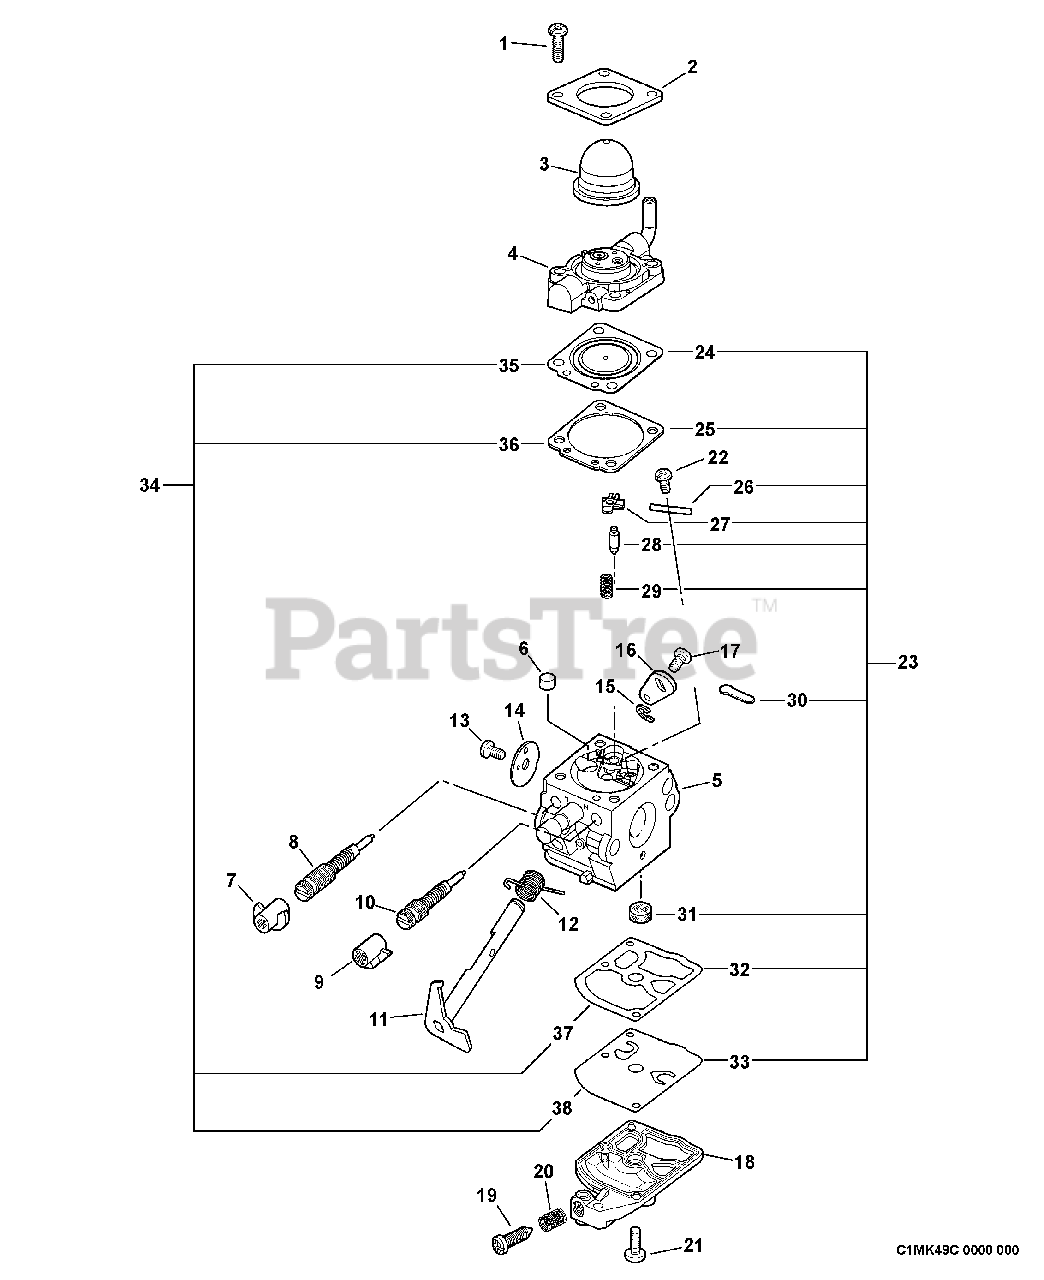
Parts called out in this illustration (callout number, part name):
2	RETAINER, PURGE BULB
3	BULB, PURGE
4	BODY ASSY, PURGE
5	BODY, CARBURETOR
6	NOZZLE, CHECK VALVE
7	CAP, LIMITER - WHITE
8	NEEDLE, LOW SPEED
9	CAP, LIMITER - RED
10	NEEDLE, HIGH SPEED
11	SHAFT, THROTTLE
12	SPRING, THROTTLE RETURN
14	VALVE, THROTTLE
16	LEVER, THROTTLE
18	COVER, PUMP
20	SPRING, IDLE ADJUST
23	REPAIR KIT
24	DIAPHRAGM, METERING
25	GASKET, DIAPHRAGM
26	PIN, METERING LEVER
27	LEVER, METERING
28	SPRING, METERING LEVER
29	VALVE, INLET NEEDLE
30	PLUG, WELCH
31	STRAINER
32	GASKET, PUMP
33	DIAPHRAGM, PUMP
34	GASKET / DIAPHRAGM KIT
35	DIAPHRAGM, METERING
36	GASKET, DIAPHRAGM
37	DIAPHRAGM, PUMP
38	GASKET, PUMP
